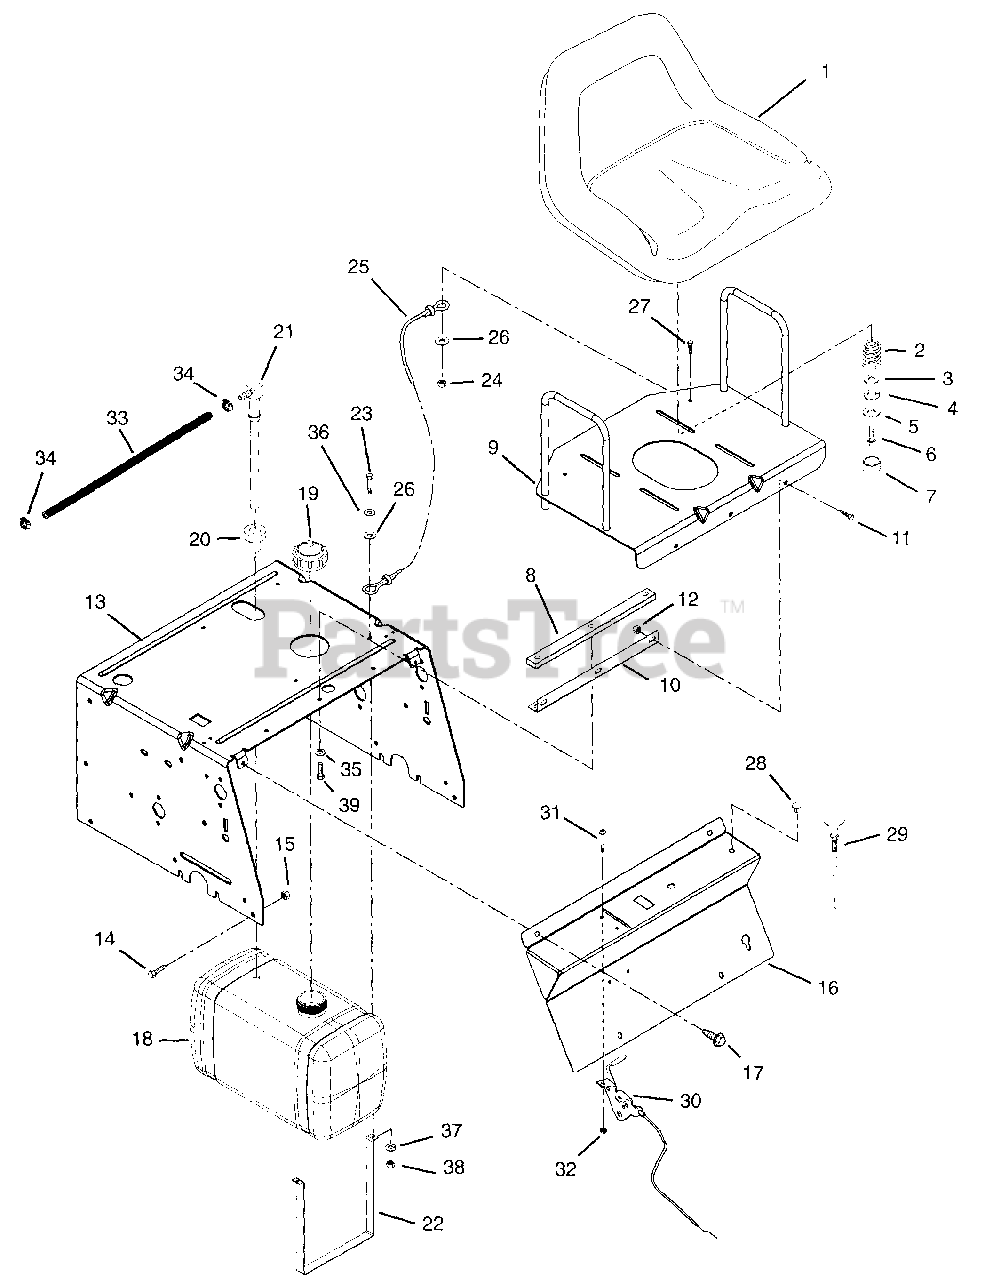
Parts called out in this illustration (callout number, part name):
2	SG-COMP .148X1.23X2.41 WLD87
3	@WSHR-FL-STL.344X.688X.065YWZC
4	@WSHR-LK .31X.078 REG YWZC
5	WSHR-FL-STL .328X.87X.179 YWZC
6	@BLT-HEX .31-18X1.00 GR5 YWZC
7	TUBE CAP
8	PLT, CLAMPING YWZC
9	SEAT PLATE WELDMENT
10	HINGE-2" X 12.88 YWZC
11	@BLT-HEX .31-18X.75 GR5 YWZC
12	@NUT-LK-CTR .31-18 YWZC
13	SUPPORT, SEAT
14	@BLT-HEX .38-16X1.00 GR5 YWZC
15	@NUT-LK-CTR .38-16 YWZC
16	CONTROL PANEL
17	@SCR-TAP .31-18X.75 HWH TR YWZ
18	FUEL TANK
19	FUEL CAP
20	BSHG-FLG .375 X 1.062 X .625 R
21	FITTING, TANK
22	STRP,FUEL TANK
23	@BLT-HEX .25-20X2.00 GR5 YWZC
24	@NUT-LK-CTR .25-20 YWZC
26	WASHER .328X1.00X.094 YWZC
27	@BLT-HEX .25-20X.75 GR5 YWZC
28	HOLE PLUG, PLASTIC .44 HOLE
29	CONTROL,CHOKE
30	CABLE THROTTLE - EZR 14 + 15HP
31	@SCR-MCH 10-24X.50 HWH YWZC
32	@NUT-LK-NYL 10-24 W/INSRT YWZC
33	HOSE, FUEL .25 ID X 22 LG
34	CLAMP-HOSE WIRE .490/.510X.116
35	WSHR-LK .312X.097 HVY YWZC
36	@WSHR-FL-STL.281X.62X.065 YWZC
37	@WSHR-LK .25X.062 REG YWZC
38	@NUT-HEX .25-20 YWZC
39	@BLT-HEX .31-18X.50 GR5 YWZC
